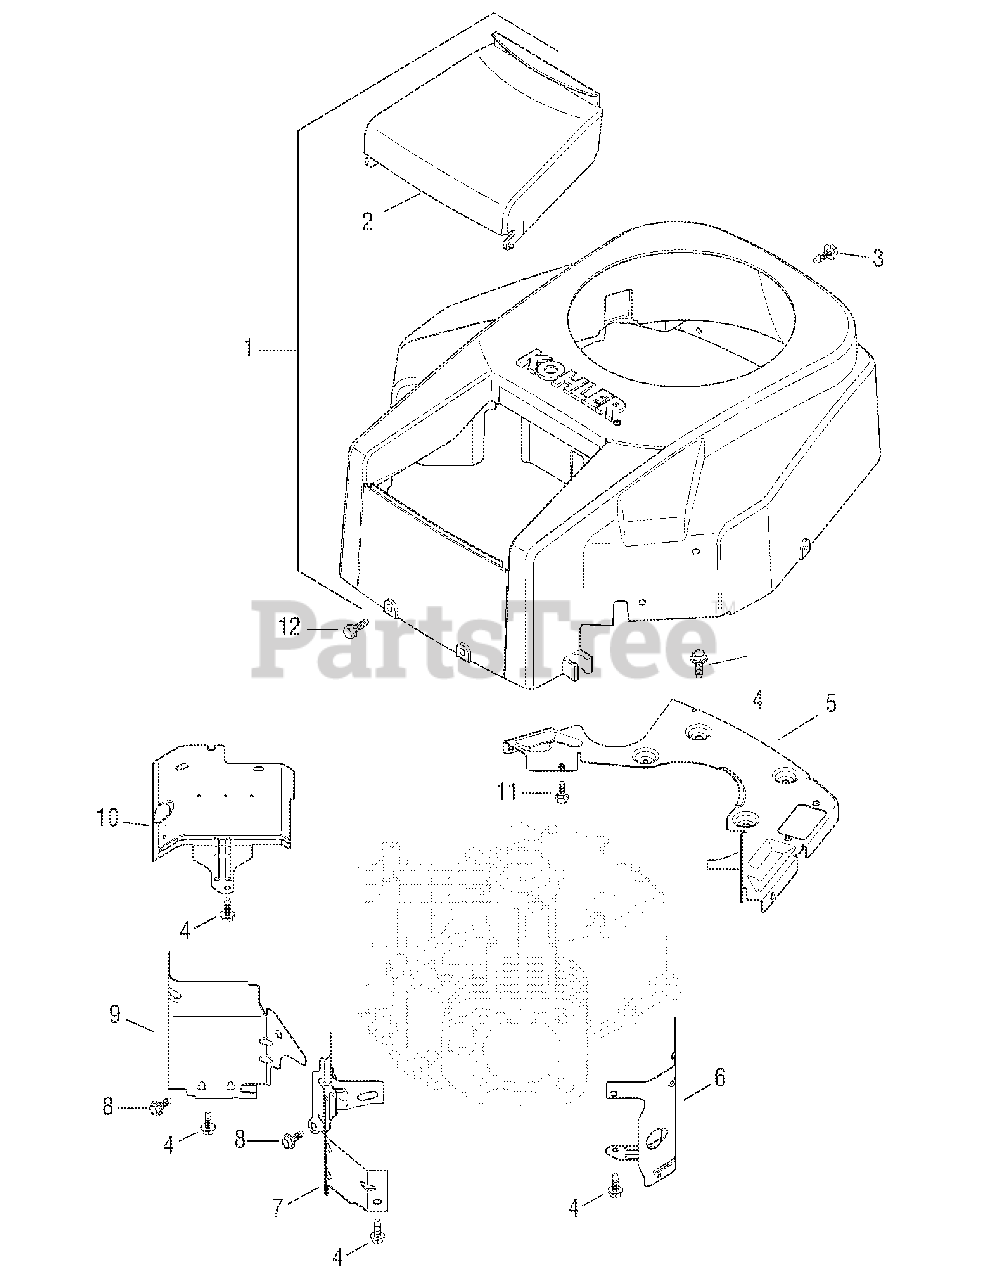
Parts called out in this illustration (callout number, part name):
1	Housing, blower (Includes 2, 41 037 10-S)
2	Cover, air cleaner
3	Screw, hex. flange M5x0.8x16
4	Screw, hex. flange M6x1.0x16
5	Plate, backing w/rectifier-regulator opening
6	Baffle, cylinder barrel - #2 side
7	Baffle, valley - #2 side
8	Screw, hex. flange M5x0.8x10
9	Baffle, valley - #1 side
10	Baffle, cylinder barrel-#1 side
11	Screw, hex. flange M5x0.8x20
12	Screw, hex. cap M6x1.7x18
